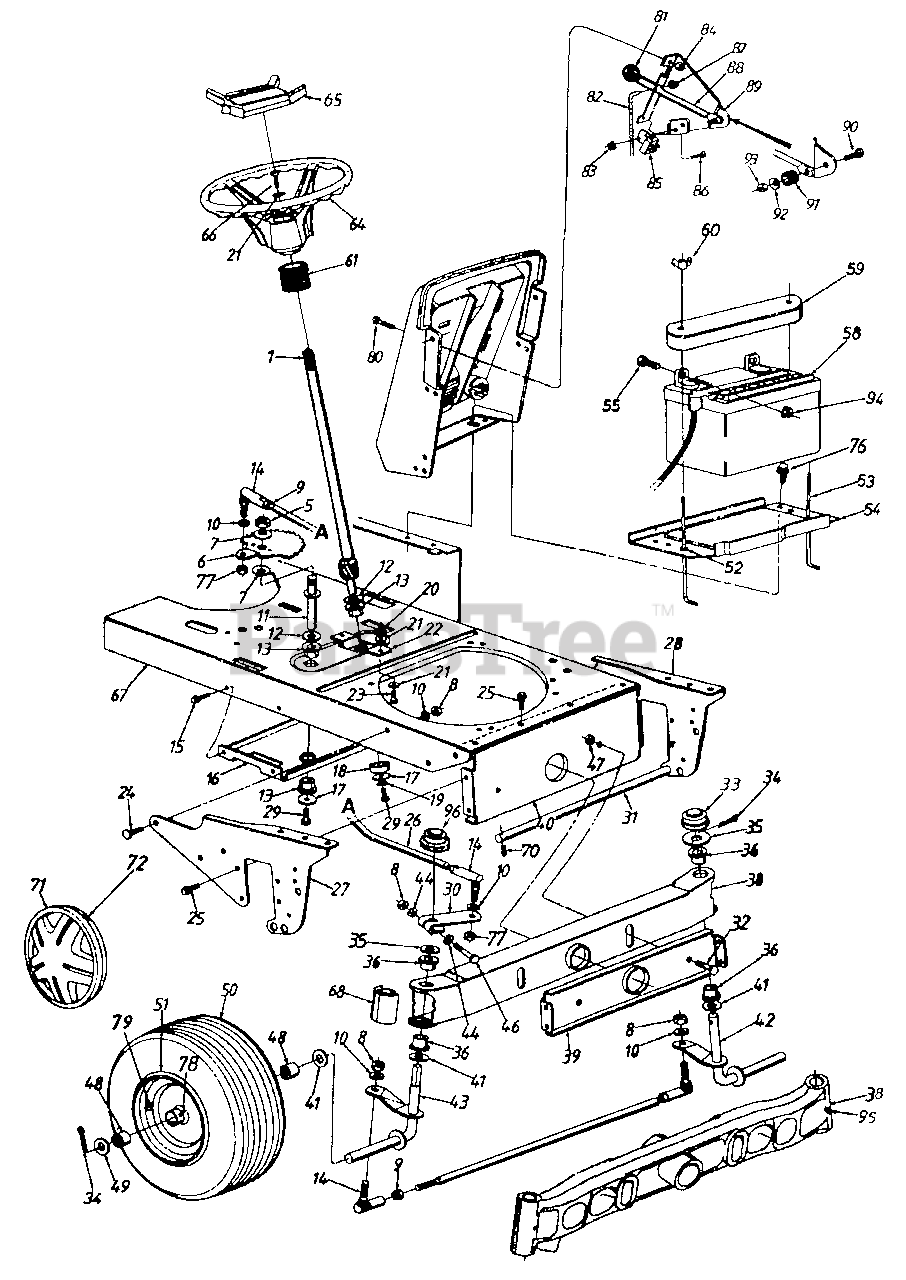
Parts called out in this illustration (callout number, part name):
1	Steering Shaft Ass'y.
5	Hex Jam Nut 5/8-18 Thd.
6	Steering Gear Segment
7	Bell-Wash. 5/8" I.D. x 1.25" O.D.
8	Hex Nut 3/8-24 Thd.
9	Hex Jam Nut 3/8-24 Thd.
10	L-Wash. 3/8" I.D.
11	Steering Gear Segment Shaft
12	Fl-Wash .64" I.D. x 1.24" O.D.
13	Hex Flange Brg .63" I.D.
14	Ball Joint Ass'y.
15	Hex Wash. Hd. TT-Tap Scr. 1/4-20 x .5" Lg.
17	Fl-Wash .33" I.D. x 1.25" O.D.
18	Spacer .985" I.D. x 1.25" O.D.
19	L-Wash. 5/16" I.D.
20	Hex Nut 5/16-24 Thd.
21	Bell-Wash .345" I.D. x .88" O.D.
24	Ribbed Neck Bolt 3/8-24 x .8" Lg.
25	Hex Wash. TT-Tap Scr. 5/16-18 x .62" Lg.
26	Steering Drag Link
31	Deck Connecting Rod
32	Shld. Bolt .498" Dia. x 2.45" Lg.
33	Cap
34	Cotter Pin 5/32" Dia.
35	Flat Washer
36	Flange Brg .757" I.D.
41	Fl-Wash .76" I.D. x 1.49" O.D.
42	Front Axle Ass'y.- L.H.
43	Front Axle Ass'y.- R.H.
44	Bowed Washer
46	Hex Bolt 3/8-24 x 2.25" Lg.
47	Hex L-Nut 3/8-16 Thd."
48	Flange Brg .75" I.D.
49	Fl-Wash .71" I.D. x 1.5" O.D.
53	Battery Hold Down Rod
58	Battery
59	Battery Cover
60	Wing Nut Plastic 1/4-20 Thd.
61	Steering Bellow
64	Steering Wheel
65	Steering Wheel Insert
66	Hex L-Bolt 5/16-18 x 1" Lg.
70	Internal Cotter Pin
71	Hub Cap
72	Spring Clip
76	Hex Wash. B-Tap Scr. 1/4 x .62" Lg.
77	Hex Jam L-Nut 3/8-24 Thd.
78	Grease Fitting
79	Air Valve
80	Truss Mach. Scr. 1/4-20 x .5" Lg
81	Shift Knob
82	Deck Control Rod
83	Hex Sems Nut #10-24 Thd.
84	Hex Sems Nut 1/4-20 Thd.
85	Safety Switch
86	Truss Mach. Scr. #10-24 x .5"
87	Push Nut
88	Blade Clutch Lever
91	Rubber Washer
92	Fl-Wash .281" I.D. x .73"
93	Hex L-Nut 1/4-20 Thd.
94	Hex Sems Nut 1/4-20 Thd.
95	Grease Fitting
